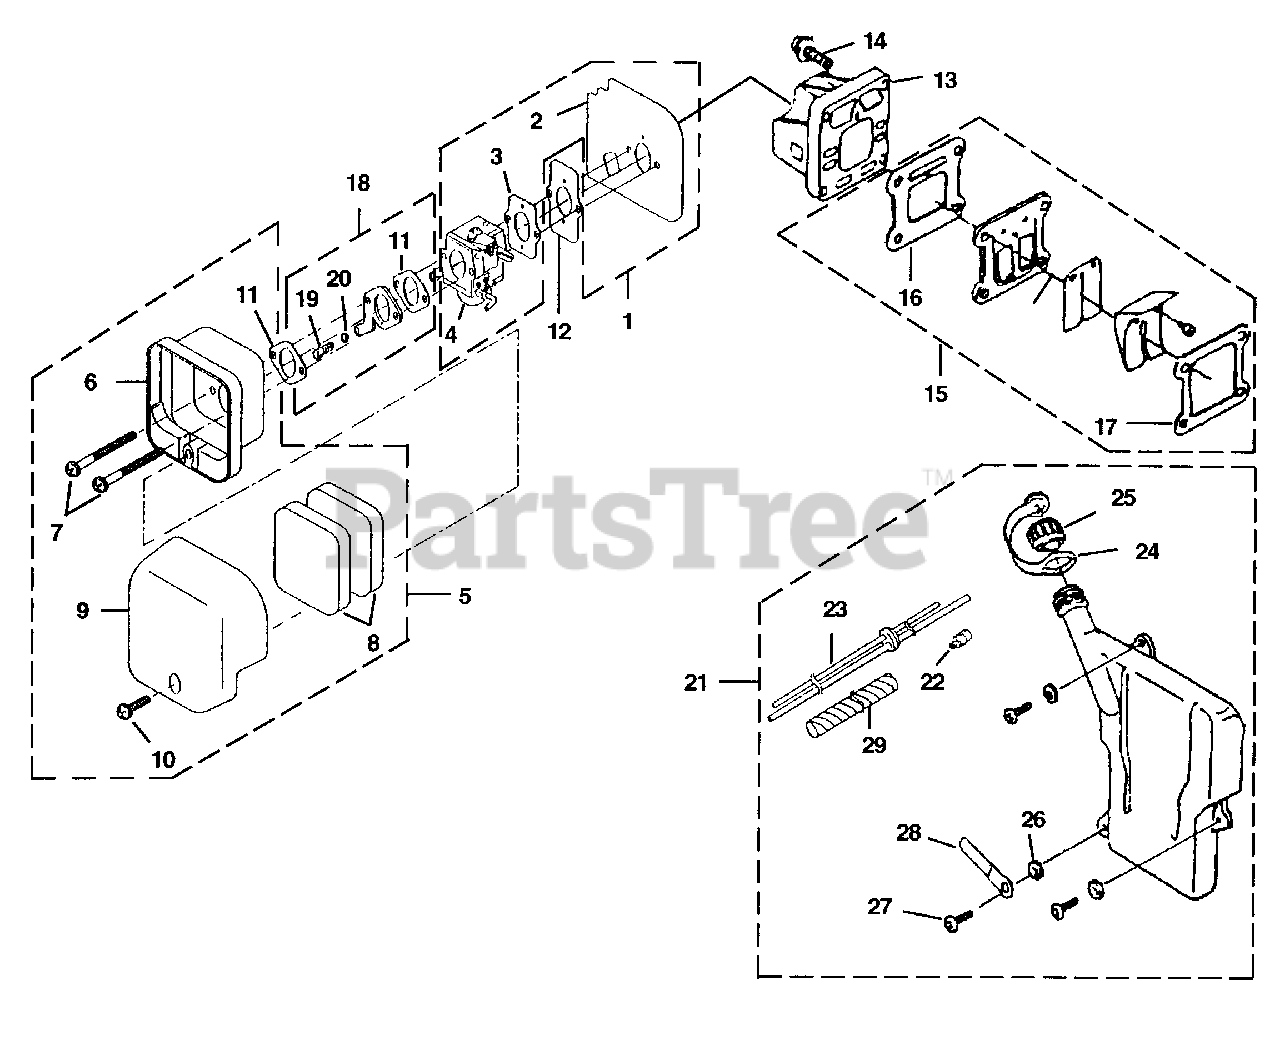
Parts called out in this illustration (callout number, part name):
1	CARBURETOR ASSEMBLY
2	GASKET-Carburetor
3	GASKET-Carburetor
4	PRIMER BULB
5	AIR FILTER ASSEMBLY
6	BODY-Air Filter
7	SCREW (M5 x 62)
8	FILTER-Air
9	COVER-Air Filter
10	SCREW ASSEMBLY
11	GASKET-Air Filter
12	PLATE-Carburetor Mounting
13	HEAT DAM
14	SCREW-Socket Hd (M5 x 20)
15	REED VALVE ASSEMBLY
16	GASKET-Heat Dam
17	GASKET-Reed Valve
18	BRACKET ASSEMBLY
19	SCREW-Cable Adjust
20	NUT (M6)
21	FUEL TANK ASSEMBLY
22	FILTER-Fuel
23	TUBE-Fuel
24	RETAINER-Cap
25	CAP-Fuel
26	WASHERS(M5)
27	SCREWS-Pan Hd (M5 x 20)
28	RETAINER-Fuel Line
29	SPIRAL RETAINER-Fuel Line
